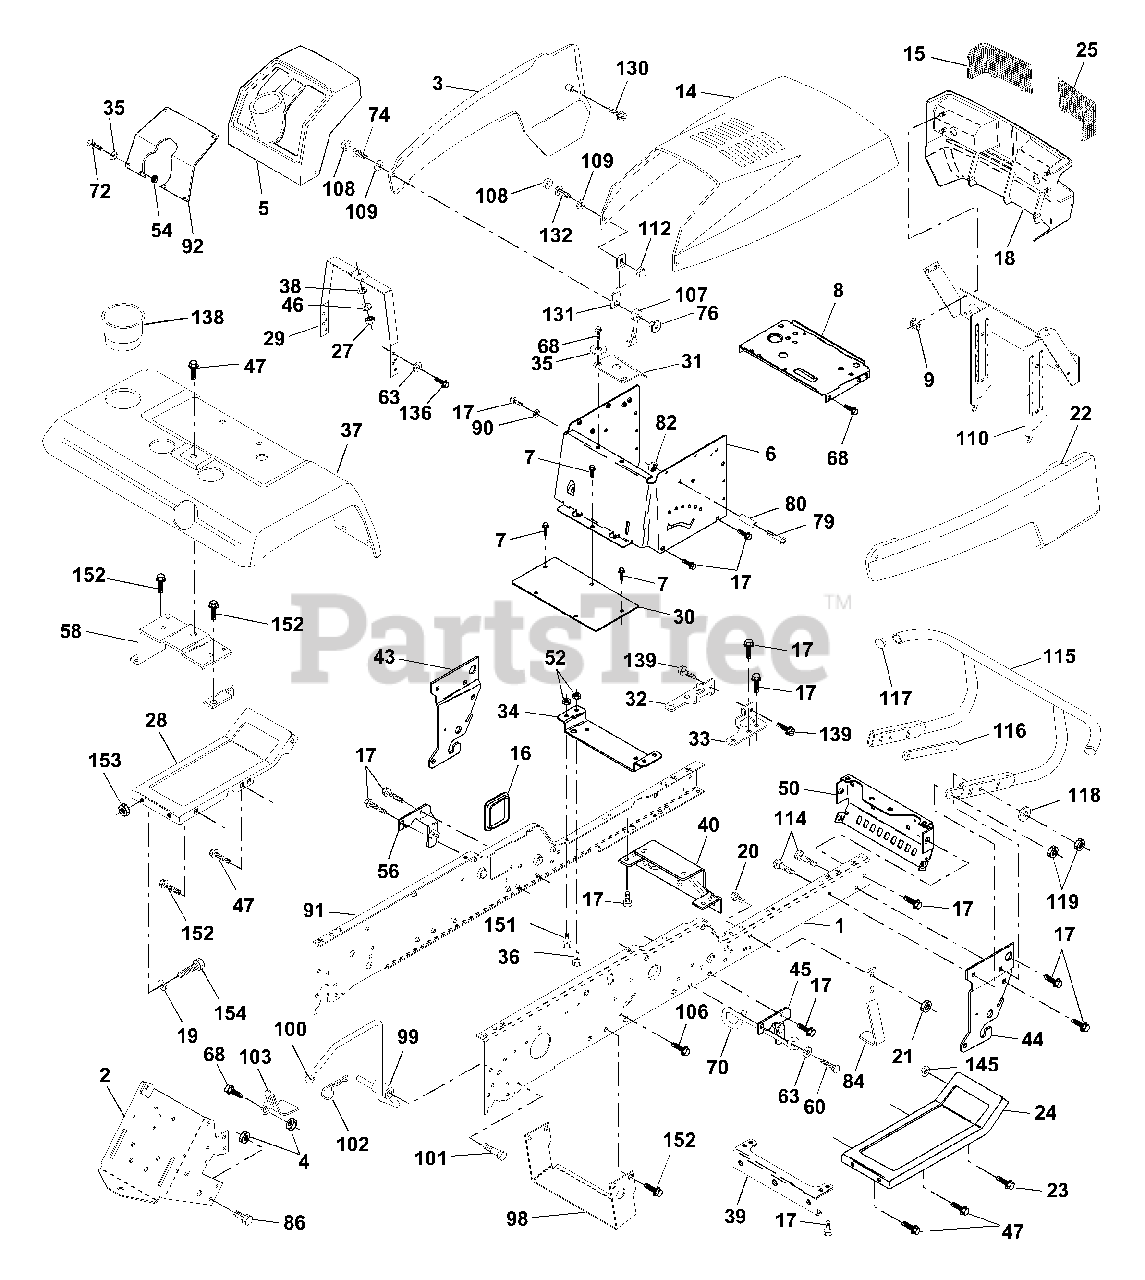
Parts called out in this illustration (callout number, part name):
1	Rail, Frame RH
2	Drawbar, Gt
3	Panel Asm., Side LH
4	Nut Crown Lock 7/16-14 Unc
5	Dash, Plastic Black
6	Dash 1-PCS, Lower
7	Screw, Thd Cut 1/4-20 x 1/2
8	Support, Battery
14	Hood Asm., Pnt
15	Lens, Headlight LH
16	Cover, Access
17	Screw, 3/8-16 x 3/4
19	Washer 13/32 x 13/16 x 12 Ga.
20	Bolt, Fin Hex 3/8-16 x 1
21	Nut, Crownlock 3/8-16 Unc
22	Panel Side RH Husqvarna YTGT
23	Screw 3/8-16 x 1/2
24	Footrest, RH
25	Lens Headlight RH
27	Nut Fin Hex 1/4-20
28	Footrest, LH
29	Bracket, Support Dash
31	Brace, Support Steering
32	Bracket Asm., Frame Pivot Lh
33	Bracket Asm., Frame Pivot Rh
34	Bracket, Engine Support Rear
35	Washer 11/32 x 11/16 x 16 Ga.
36	Bolt, Fin Hex 5/16-18 x 3/4
37	Fender, Pnt.
38	Washer, Lock 1/4
39	Bracket, Axle Front
40	Bracket, Support Axle/Engine
43	Bracket, Spnsn Front Lh
44	Bracket, Spnsn Front Rh
45	Bracket Asm., Susp Chassis Rh
46	Washer 9/32 x 3/4 x 16 Ga.
47	Screw Thdrol 3/8-16 x 1/2
50	Bracket, Chassis Front
52	Locknut, Hex W/Ins 5/16-18 Unc
54	Nut 5/16-18
56	Bracket Asm., Susp Chassis Lh
58	Bracket Asm., Fender
60	Screw Thdrol 3/8-16 x 1-1/4
63	Washer 13/32 x 1 x 14 Ga.
68	Screw, Thdrol 5/16-18 x 1/2
70	Guide, Belt Mid Span
72	Screw, Mach Trhd 5/16-18 x 3/4
74	Screw, Machine #10-24
76	Nut, Weld #10-24
79	Screw, Machine #10-24 x 1/4
80	Spacer, Split
82	Nut #10-24
84	Stop, Over Center 44" 20/23" T. 94
86	Bolt, Fin Hex 7/16-14 Unc x 1
90	Washer, Lock External Tooth 3/8
91	Rail, Frame Lh
92	Plate, Silkscreen Dash
98	Bracket Chassis Skid
99	Rod Asm. Bypass
100	Cap Brake Parking Red
101	Screw Thdrol. 3/8-16 x 1-3/4
102	Retainer Spring 1"
103	Bracket Lock Bypass
106	Screw Thdrol. Hex Hd Zinc Mwr
107	Latch, Chute Blk
108	Cap, Snap Black
109	Cap, Washer Snap
110	Pivot Asm. Grille/Hood Husq. VGT
112	Nut, Acorn, Hex #10-24
114	Bolt, Carriage 3/8-16 x 1-1/4
115	Bumper Asm.
116	Bracket Extension Bumper
117	Plug Plastic
118	Washer 13/32 x 13/16 x 16 Ga.
119	Nut Crownlock 3/8-16 UNC
130	Screw, Hw Hd Hi-Lo #13-16 x 3/4
131	Bracket Support Hood/Panel YP
132	Screw Truss Hd. #10-24 x 3/8
136	Screw 3/8-16 x 3/4
138	Cupholder YTGT Grey
139	Bolt, Shoulder 5/16-18
145	Washer, Flat 13/32 x 7/8 x 14 Ga.
151	Screw 5/16-18 x 3/4
152	Screw 3/8-16 x 3/4
153	Nut Crown Lock 3/8-16 Unc
154	Bolt Hex Fin 3/8-13 x 1" Blk
